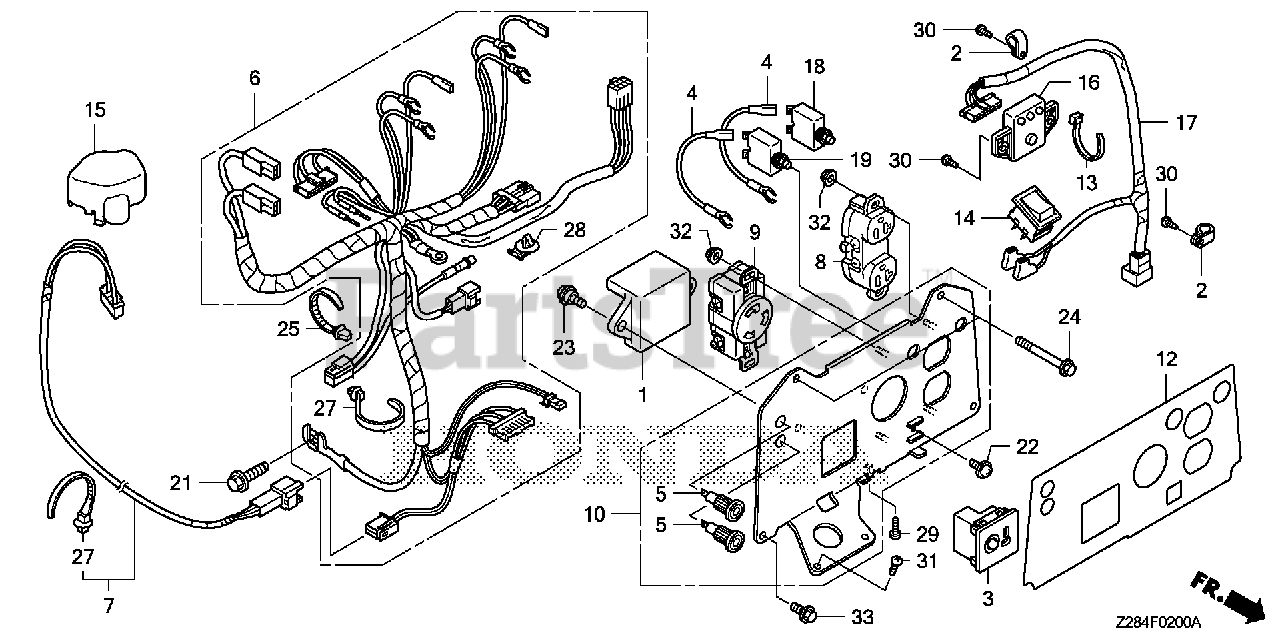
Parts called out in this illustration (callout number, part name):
1	SPARK UNIT
2	CLAMP F, CABLE
3	RECEPTACLE, D.C.
4	SUB-WIRE ASSY.
5	SOCKET, COMPOSITE
6	WIRE HARNESS ASSY., CONTROL
7	SUB-WIRE ASSY.
8	RECEPTACLE ASSY. (125V-20A) (MATSUSHITA)
9	RECEPTACLE (3-PRONG) (30A/125V)
10	PANEL, CONTROL
12	MARK, CONTROL PANEL
13	TIE, CABLE (C)
14	SWITCH ASSY., IDLE CONTROL
15	COVER, THROTTLE MOTOR
16	INDICATOR ASSY.
17	HARNESS ASSY., INDICATOR
18	PROTECTOR, CIRCUIT (20A)
19	PROTECTOR, CIRCUIT (30A)
21	BOLT, FLANGE (6X14)
22	SCREW, PAN (5X12) (GROUND CABLE)
23	SCREW, PAN (5X13)
24	BOLT, FLANGE (6X57)
25	TIE, CABLE
27	CLIP, HARNESS BAND (145MM) (BLACK)
28	CLIP, CONNECTOR (RED)
29	SCREW, PAN (5X8)
30	SCREW, TAPPING (5X12)
31	SCREW, TAPPING (5X16)
32	NUT, FLANGE (4MM)
33	BOLT, FLANGE (6X10)
